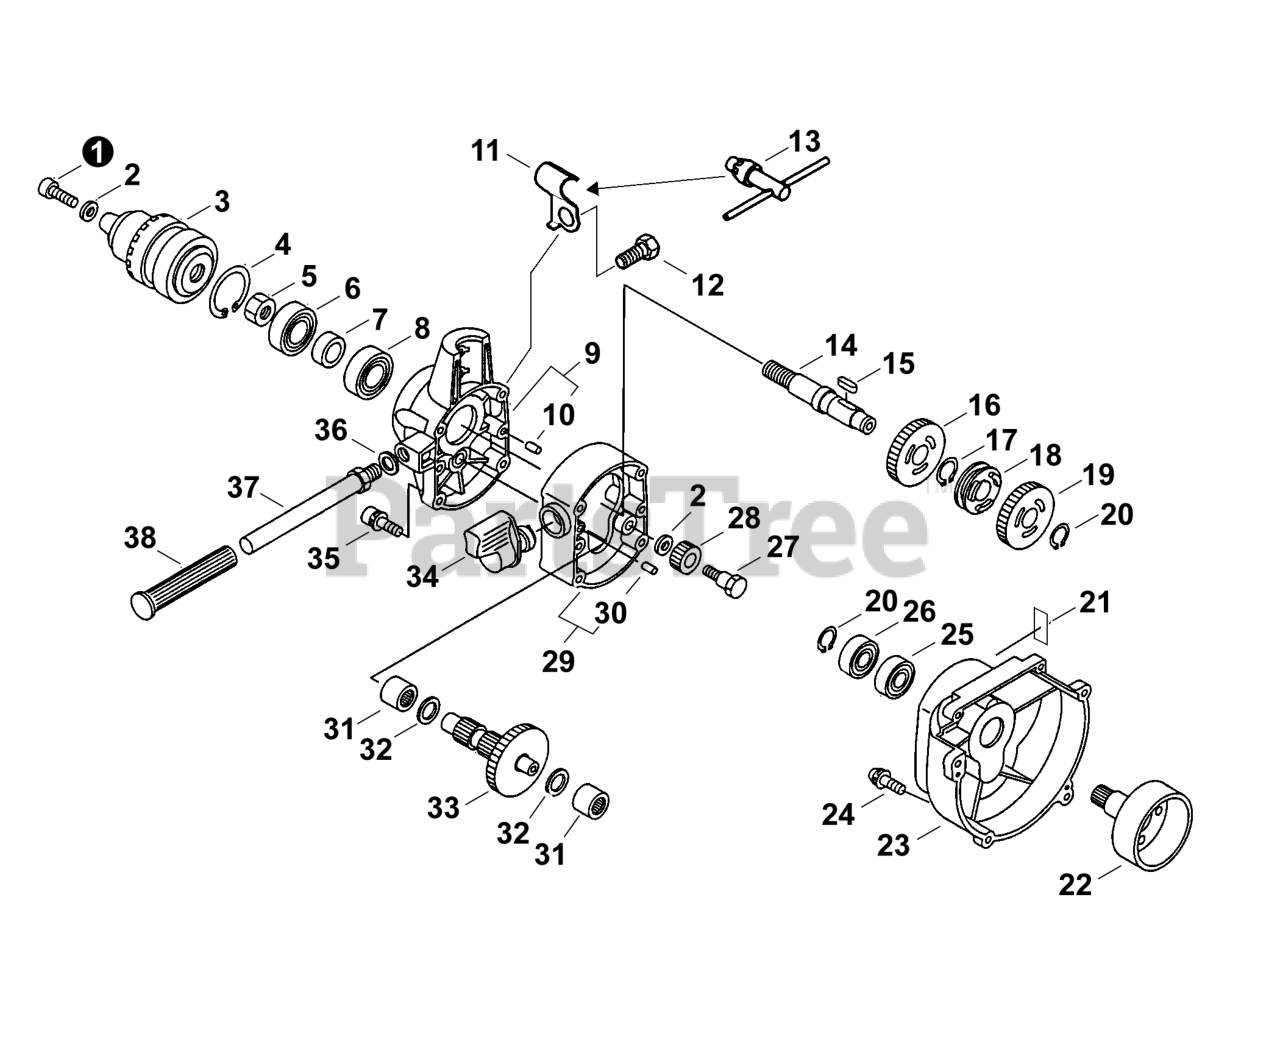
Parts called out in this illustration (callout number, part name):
1	BOLT 6×20
2	WASHER 6
3	CHUCK, KEYED
4	RING, SNAP Ø32
6	BEARING, BALL 6002 DDU
8	BEARING, BALL 6002
9	HOUSING, GEAR CASE
10	PIN, LOCATING 4×8
11	HOLDER, CHUCK KEY
12	BOLT 10×1.5×15
13	KEY, CHUCK
14	SHAFT, AXLE
15	KEY, WOODRUFF 4×16
16	GEAR, SPUR
17	RING, RETAINING 15
18	NAIL, CLUTCH
19	GEAR, SPUR
20	RING, SNAP 12
21	LABEL - CAUTION - HOT
22	DRUM, CLUTCH
23	COVER, FAN
24	SCREW 4×16
25	BEARING, BALL 6001 DDU
26	BEARING, BALL 6001
27	BOLT, CLUTCH
28	GEAR, SPUR
29	CASE, GEAR
30	PIN, LOCATING 4×8
31	BEARING, NEEDLE
33	GEAR, SHAFT
34	LEVER, CLUTCH
35	BOLT 5×50
36	WASHER 10.5×18×1.6
37	HANDLE, FRONT
38	GRIP, HANDLE
